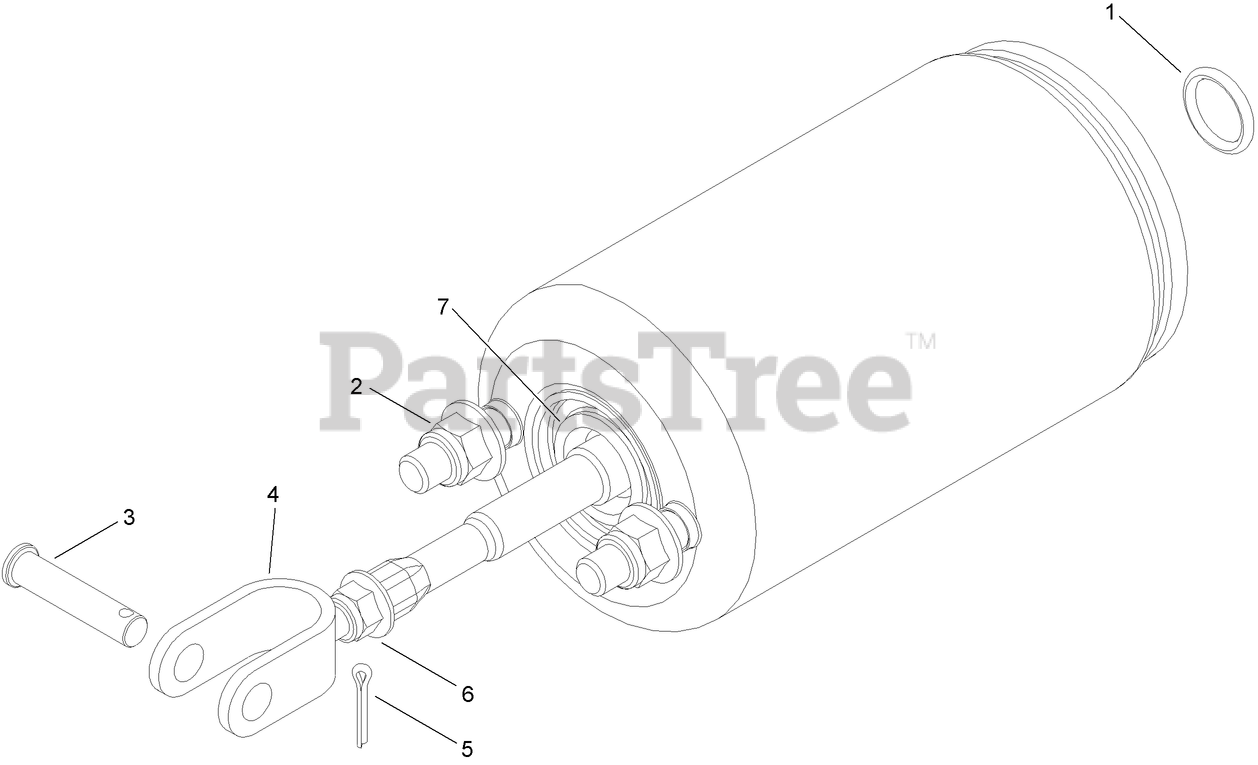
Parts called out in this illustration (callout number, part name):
1	O-RING
2	NUT-HEX
3	PIN-CLEVIS
4	CLEVIS
5	PIN-COTTER
6	NUT-HEX
7	BOOT-DUST
